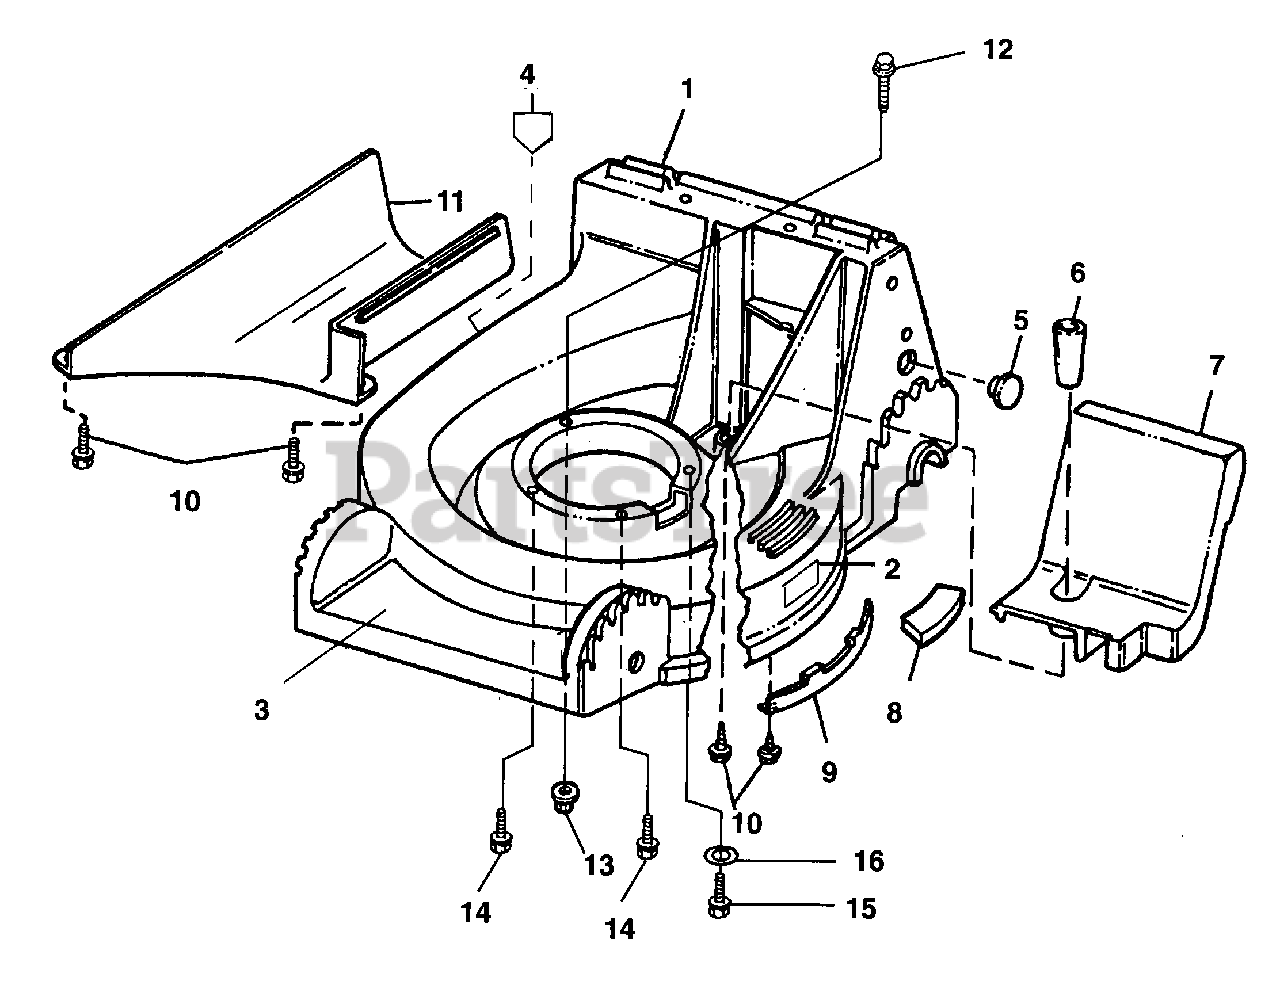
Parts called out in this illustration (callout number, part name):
1	DECK WITH DECALS
3	LABEL, Product ID
5	GROMMET
9	GUARD LH
10	SCREW
11	DEFLECTOR
12	BOLT
13	NUT, Lock
14	SCREW
